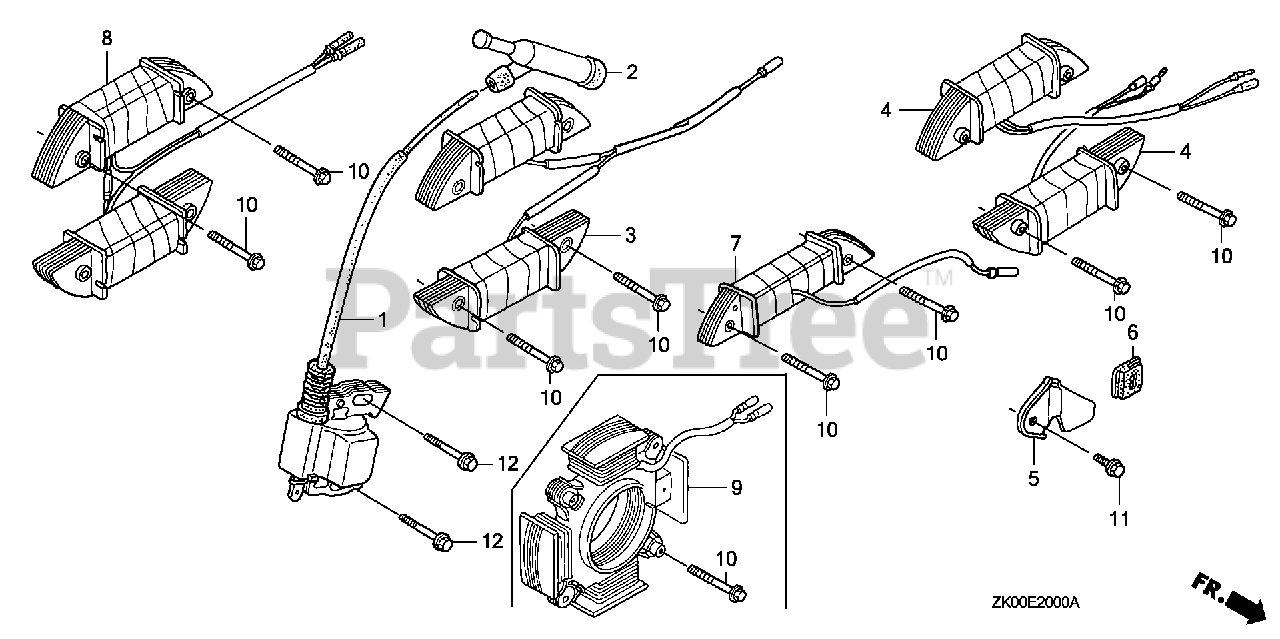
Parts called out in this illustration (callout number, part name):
1	COIL ASSY., IGNITION
2	CAP ASSY., NOISE SUPPRESSOR (NICHIWA Y-EZ RTFM256)
5	CLAMP, WIRE
6	GROMMET, WIRE
9	COIL ASSY., CHARGE (12V-7A)
10	BOLT, FLANGE (6X28) (CT200)
11	BOLT, FLANGE (5X10)
12	BOLT, FLANGE (6X25) (CT200)
